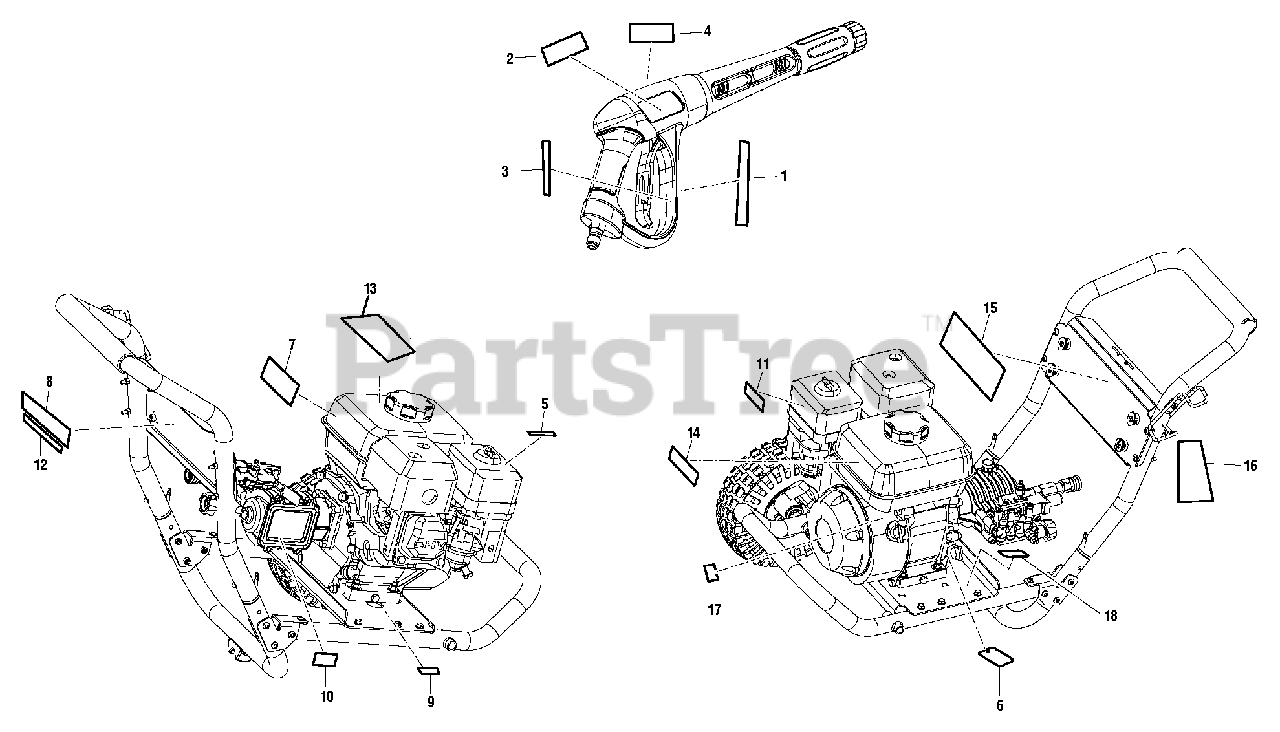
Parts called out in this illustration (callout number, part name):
1	Trigger Handle Rating Label
2	Trigger Handle Logo Label
3	Trigger Handle Warning Label (Fr/Sp)
4	Trigger Handle Warning Label (Eng)
5	Hot Surface Label
6	Oil Dipstick Hang Tag
7	Danger Label
8	Quick Start Label
9	Combustion Warning Label
10	Logo Label
11	Choke & Fuel Label
12	Inquiries Label
13	Warning Hang Tag
14	E85 Label
15	Performance Label
16	Nozzle Hang Tag
17	Engine Switch Label
18	Add Oil Label
